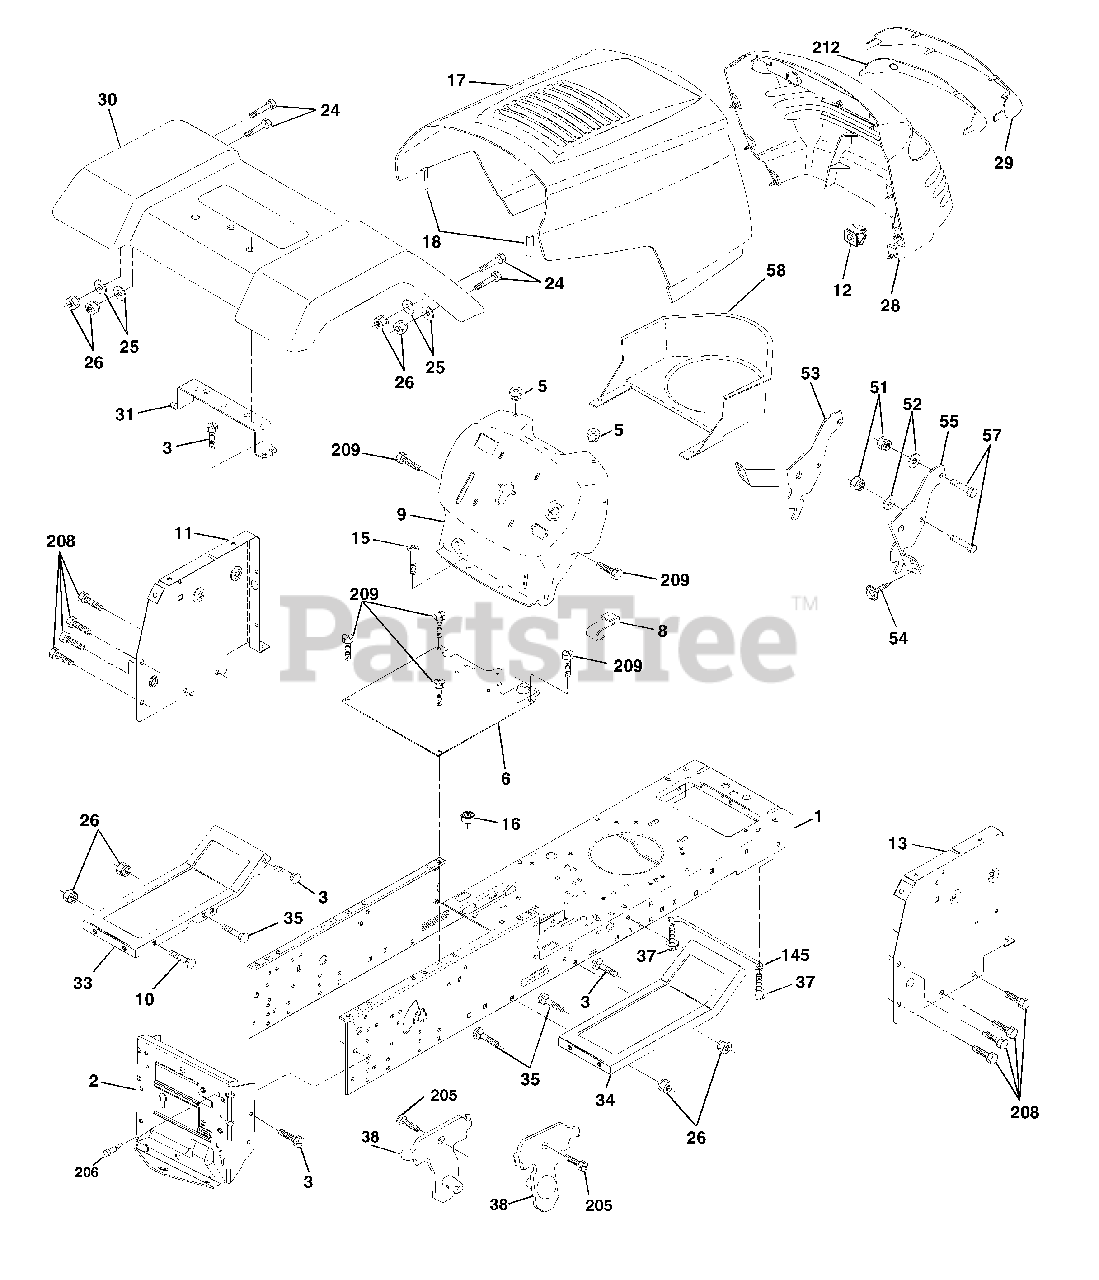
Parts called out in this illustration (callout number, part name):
1	Chassis
2	Drawbar
3	Screw 3/8-16 x 3/4
5	Bumper Hood/Dash
6	Saddle Slkscr Flat Lt 6 Sp
8	Clip Retainer Slide-On
9	Dash
10	Bolt Rd Hd Sqnk. 3/8-16 Unc x 1
11	Panel Asm. Dash Lh
12	Clip Tinnerman Grile P/L
15	Screw Mach Trhd 5/16-18 Unc x 3/4
16	Nut Keps 5/16-18 Unc
17	Hood
18	Bumper Hood
24	Bolt Fin Hex 3/8-16 Unc x 1 Gr. 5
25	Washer 13/32 x 13/16 x 12 Ga.
26	Nut Lock Hex w/Insert 3/8-16 UNC
28	Grill/Lens Asm
29	Lens Grille Private label
30	Fender Asm
31	Bracket Fender
33	Footrest
34	Footrest
35	Bolt Rd Hd Sht. Sqnk. 3/8-16 x 3/4
37	Screw Thdrol 5/16-18 x 1/2 Tyt
38	Bracket Asm. Pivot Mower Rear
51	Nut Lock Hex W/Ins. 1/4-20
52	Washer 9/32 x 7/8 x 16 Ga.
53	Bracket Grille LH
54	Screw Hex Wshd 8-18 x 7/8
55	Bracket, Grille RH
57	Bolt Fin Hex 1/4-20 x .75
58	Air Duct Private Label
145	Rod Pivot Chassis/Hood
205	Screw Thdrol 3/8-16 x 1/2
206	Bolt shoulder 5/16-18
208	Screw Thdrol 3/8-16 x 1/2
209	Screw Hex Wsh Thdrol 3/8-16
212	Insert Lens Reflector
